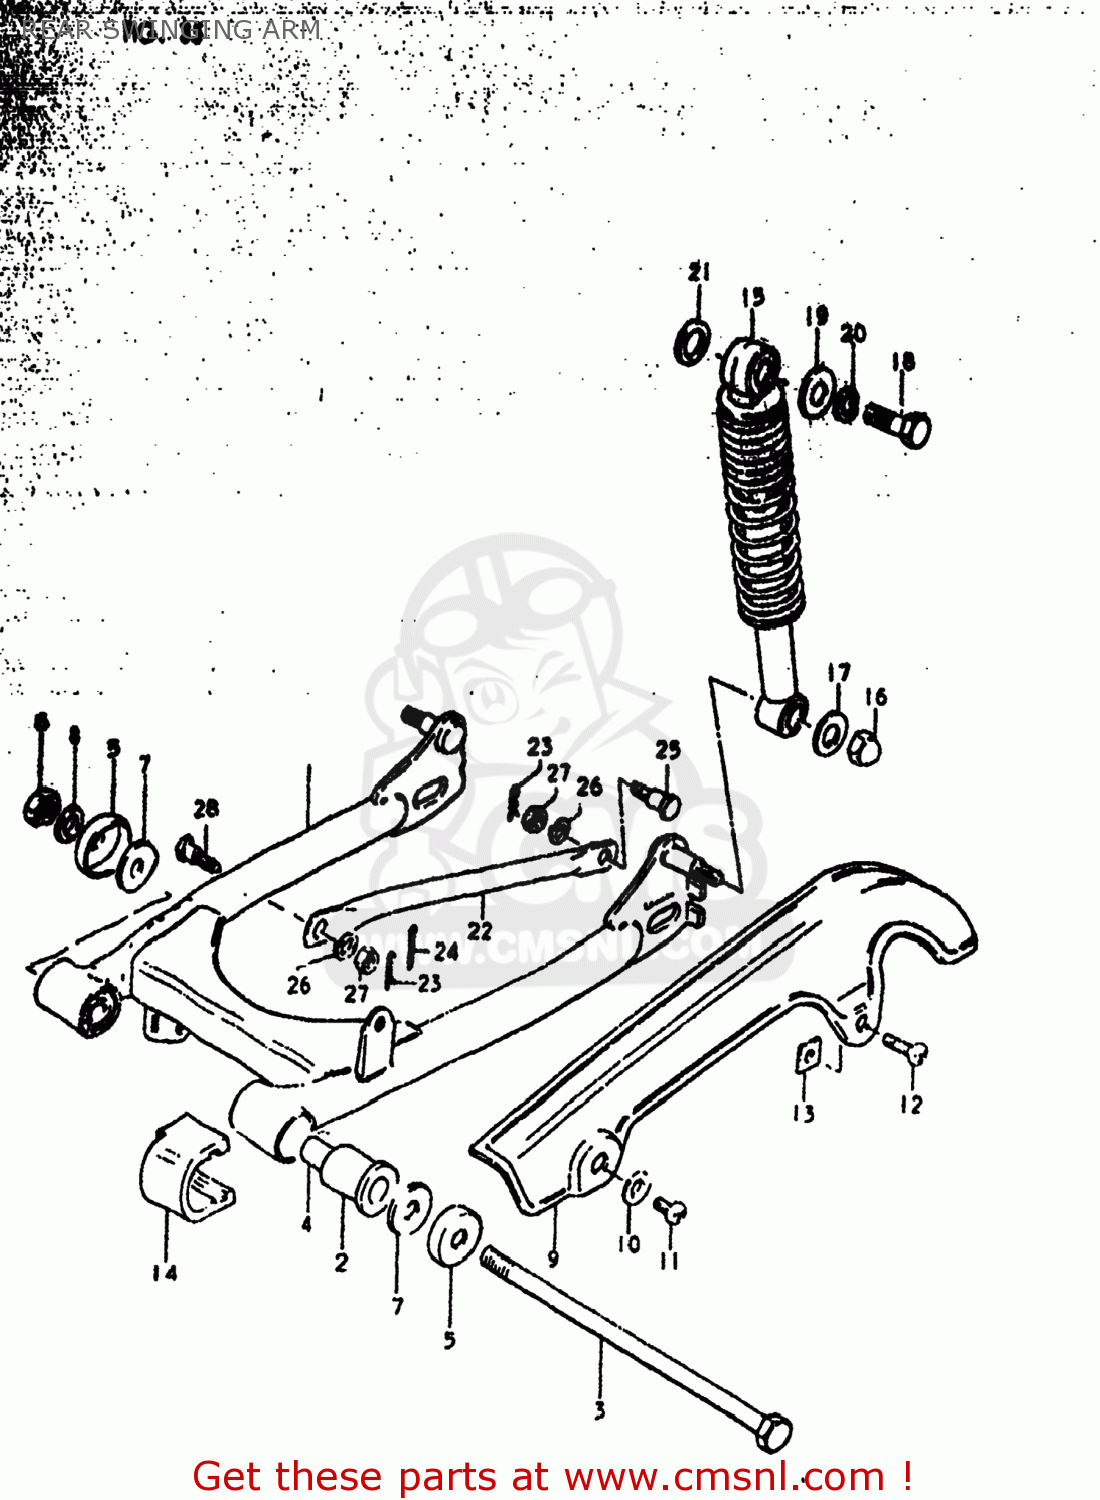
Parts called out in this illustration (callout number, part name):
1	SWING ARM ASSEMBLY,REAR
2	BUSHING
3	SHAFT, PIVOT
4	SPACER,RR SWGARM PIVOT
5	COVER,REAR SWING ARM DUST
6	NUT
7	WASHER (10.2X28X1.5)
8	WASHER
9	CASE,CHAIN
10	WASHER
11	SCREW
12	SCREW 6X12
13	NUT,CHAIN CASE RR
14	BUFFER,CHAIN TOUCH DEFLECTOR
15	ABSORBER ASSEMBLY,REAR SHOCK
16	NUT, LOWER LH
17	WASHER
18	BOLT
19	WASHER (6.5X24X1.6)
20	LOCK WASHER
21	WASHER
22	TORQUE LINK,REAR
23	CLIP
24	COTTER PIN
25	BOLT(8X26.5)
26	LOCK WASHER
27	NUT
28	BOLT(8X22)
